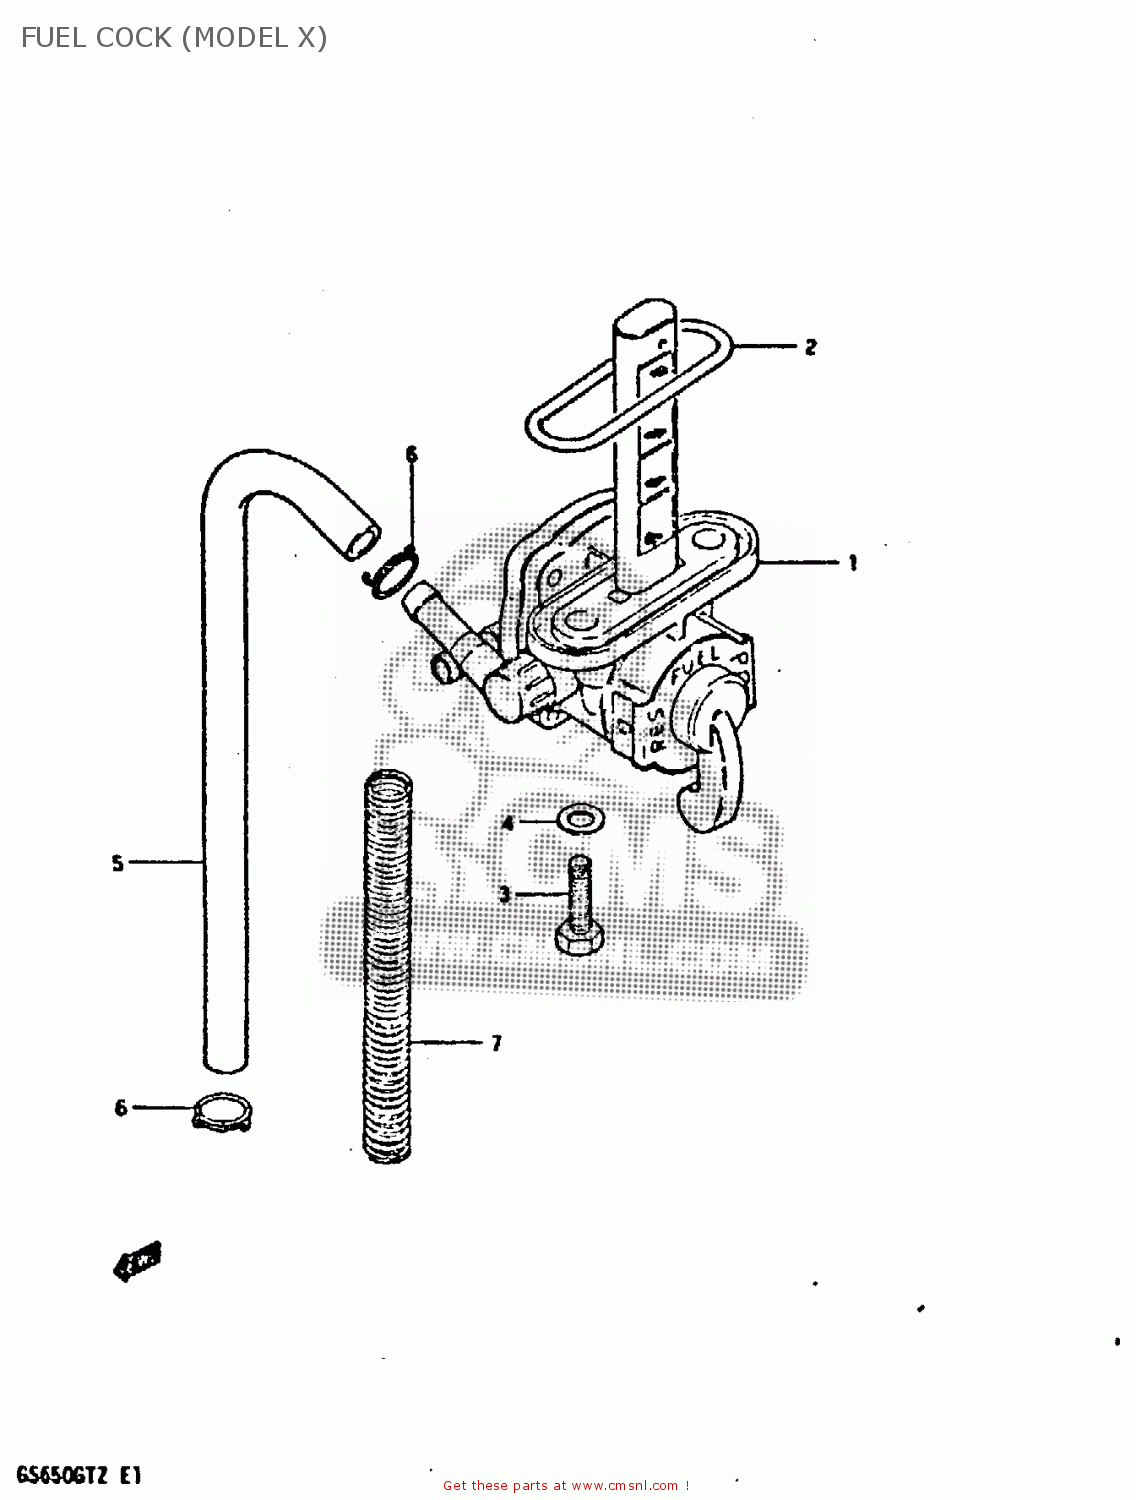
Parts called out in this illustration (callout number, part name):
1	COCK ASSEMBLY,FUEL
2	O RING
3	BOLT(6X20)
4	GASKET
5	HOSE
6	CLIP
7	SPRING
